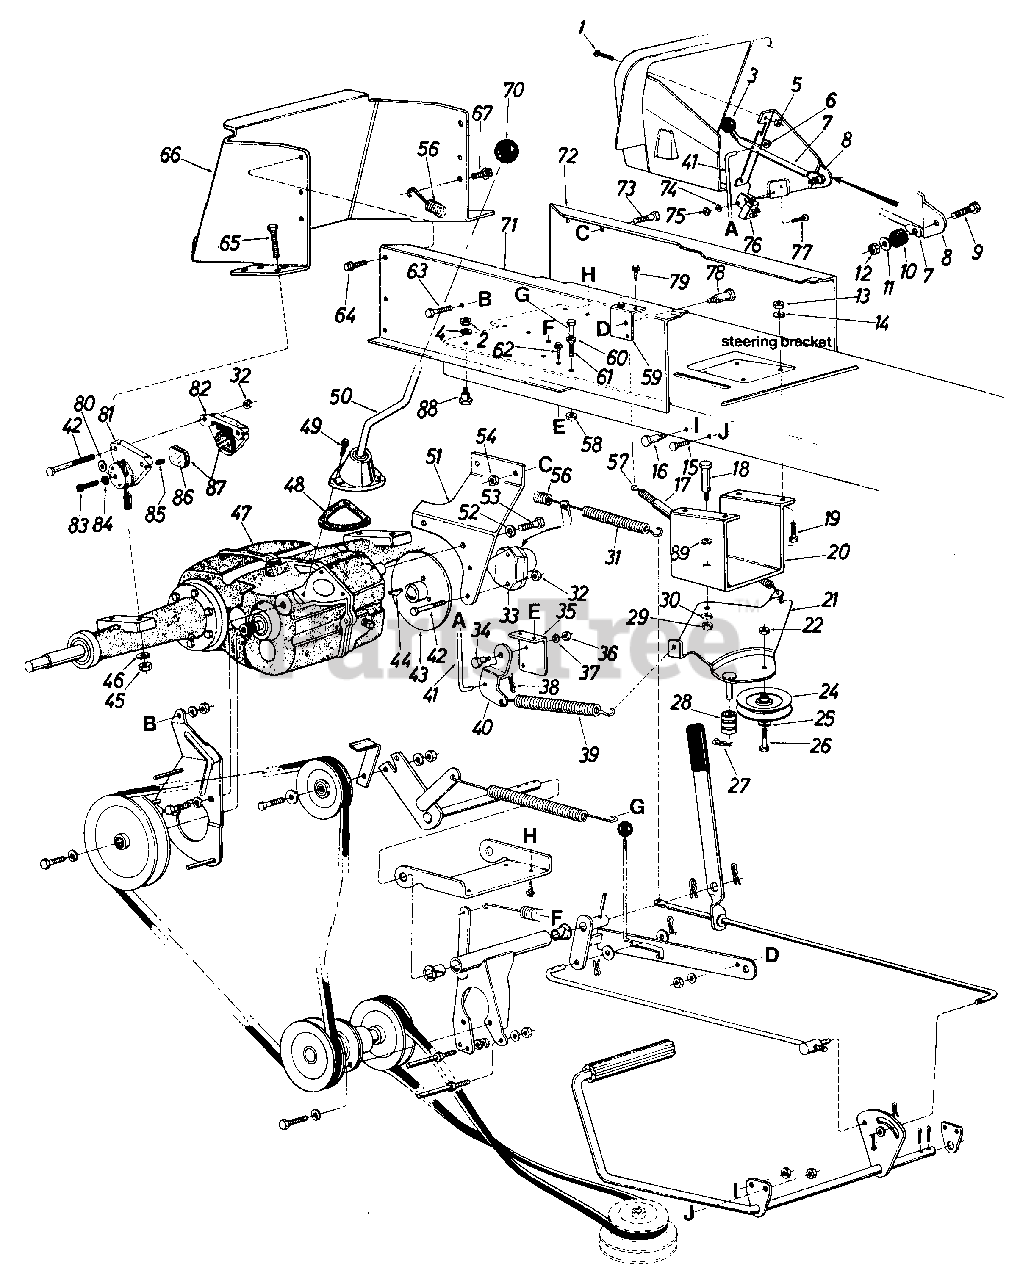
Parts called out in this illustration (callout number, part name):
1	Truss Mach. Scr. 1/4-20 x .50" Lg.
2	Hex Nut 1/4-20 Thd.
3	Knob Blade Clutch
4	L-Wash. 1/4 I.D.
5	Hex Sems Nut 1/4-20 Thd.
6	Push Cap 1/4" Rod
7	Blade Clutch Lever
8	Deck Clutch Control Brkt.
9	Hex Scr. 1/4-20 x 1.25" Lg.
10	Rubber Wash. .330 I.D. x .87
11	Fl-Wash. 1/4" I.D. x .75" O.D. x .057
12	Hex Cent. L-Nut 1/4-20 Thd.
13	Hex Nut 5/16-18 Thd.
14	L-Wash. 5/16" Scr.
15	Hex Scr. 3/8-16 x .62" Lg.
16	Shld. Scr. 1/2" Dia. x .335 0 Lg. 3/8-16
17	Convoluted Conduit .50 I.D. x 4" Lg.
18	Shld. Scr. 7/16 Dia. x .16" 5/16-18
19	Hex Scr. 5/16-18 x 1.00" Lg.
20	Idler Mtg. Brkt. Deck
21	Idler Brkt. Ass'y.
22	Hex L-Nut 3/8-16 Thd.
24	4" "V" Idler Pulley
25	Fl-Wash. 3/8" I.D.
26	Hex Scr. 3/8-16 x 1.25" Lg.
27	Hairpin Cotter 5116" Rod
28	Spacer
29	Hex Nut 5/16-18 Thd.
30	L-Wash. 5/16" Scr.
31	Ext. Spring Brake Rod
32	Hex Cent. L-Nut 3/8-16 Thd.
33	Disc Brake Caliper Ass'y.
34	Shld. Scr. 7/16" Dia. x .16" Lg. 5/16-18
35	Parking Brake Cam Mtg. Brkt.
36	Hex Nut 5/16-18 Thd.
37	L-Wash. 5/16" Scr.*
38	Hairpin Cotter 5/16" Dia.
39	Ext. Spring Deck Control
40	Deck Control Pivot Brkt.
41	Deck Control Rod
42	Hex Scr. 3/8-16 x 2.50" Lg.
43	Hub & Disc Ass'y. (For Brake)
44	Hi-Pro Key 3/16 x 314" Lg.
45	Hex Nut 3/8-16 Thd.
46	L-Wash. 3/8" Scr.*
47	Transaxle
51	Transaxle Support
52	L-Wash. 3/8" Scr.*
53	Hex Scr. 3/8-16 x .75" Lg*
54	Hex L-Nut 3/8-16 Thd.
56	Ext. Spring Brake Return
57	Ext. Spring Deck Idler Return
58	Hex L-Nut 5/16-18 Thd.
59	Parking Brake Cam Mtg. Brkt.
60	Hex Nut 5/16-18 Thd.*
61	Hex Scr. 5/16-18 x 1.50" Lg
62	Hex Thd. Rolling Scr. 1/4-20 x .50" Lg.
63	Hex Scr. 3/8-16 x .75" Lg.*
64	Hex AB-Tap Scr. 5/16 x .75" Lg.
65	Hex Scr. 3/8-16 x 1.50" Lg.*
66	Hitch Plate
67	Hex Thd. Rolling Scr. 5/16-24 x .75" Lg.
70	Knob Transaxle
71	Side Panel Upper Frame R.H.
72	Side Panel Upper Frame L.H .
73	Hex Scr. 3/8-16 x .75" Lg.*
75	Hex Nut #10-24 Thd.*
76	Safety Switch (Deck)
77	Truss Mach. Scr. #10-24 x .50" Lg.*
78	Shld. Scr. 7/16" Dia. x .16" Lg. 5/16-18
79	Hex Thd. Rolling Scr. 1/4-20 x .50" Lg.
80	Washer
81	Housing with Lever & Pin
82	Anvil
83	Pin, Adjuster
85	Pin, Actuator
86	Backing Plate
87	Lining
88	Shld. Bolt .375" Dia. x .180 0 Lg. 1/4-20 Thd.
89	Wave Washer
